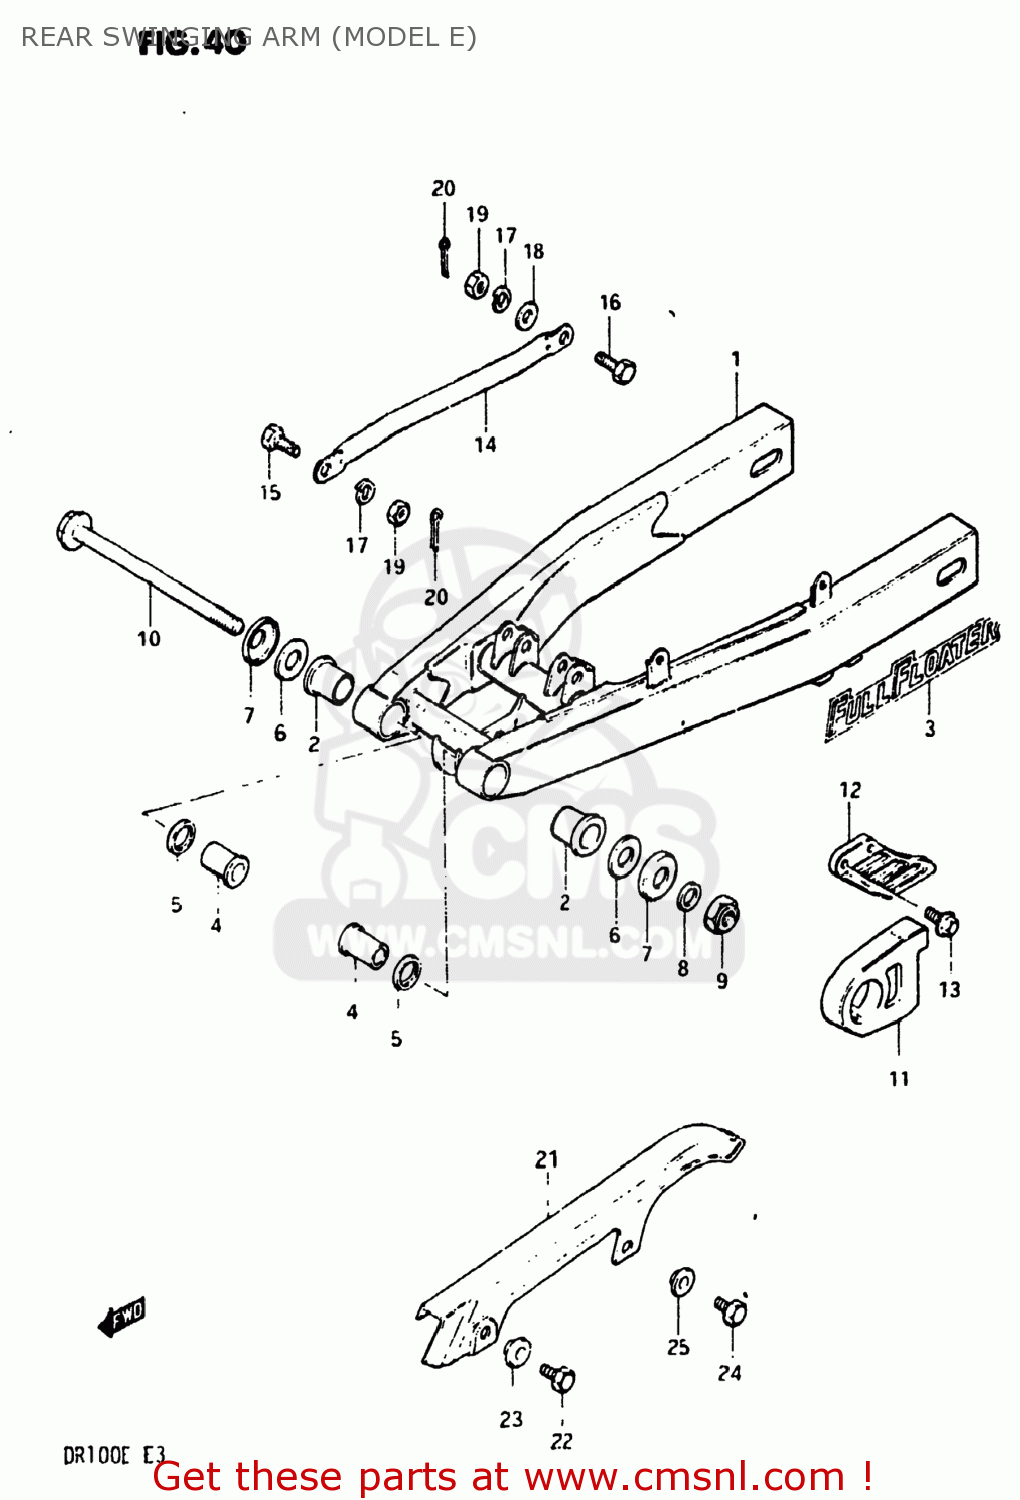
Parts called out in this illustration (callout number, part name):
1	SWING ARM ASSEMBLY,REAR
2	BUSHING,REAR SWING ARM PIVOT
3	EMBLEM
4	SPACER,RR SWGARM PIVOT
5	SEAL,OIL(20X27X5)
6	WASHER
7	CVR,RR SWGARM DUST SEAL(OD:40)
8	WASHER
9	NUT 14MM
10	SHAFT,REAR SWING ARM
11	BUFFER,CHAIN TOUCH DEFLECTOR
12	GUIDE,CHAIN
13	BOLT
14	LINK,REAR TORQUE
15	BOLT(8X22)
16	BOLT(8X26.5)
17	LOCK WASHER
18	WASHER
19	NUT
20	PIN 20X20
21	CASE,CHAIN
22	BOLT 6X8
23	WASHER
24	BOLT
25	WASHER
